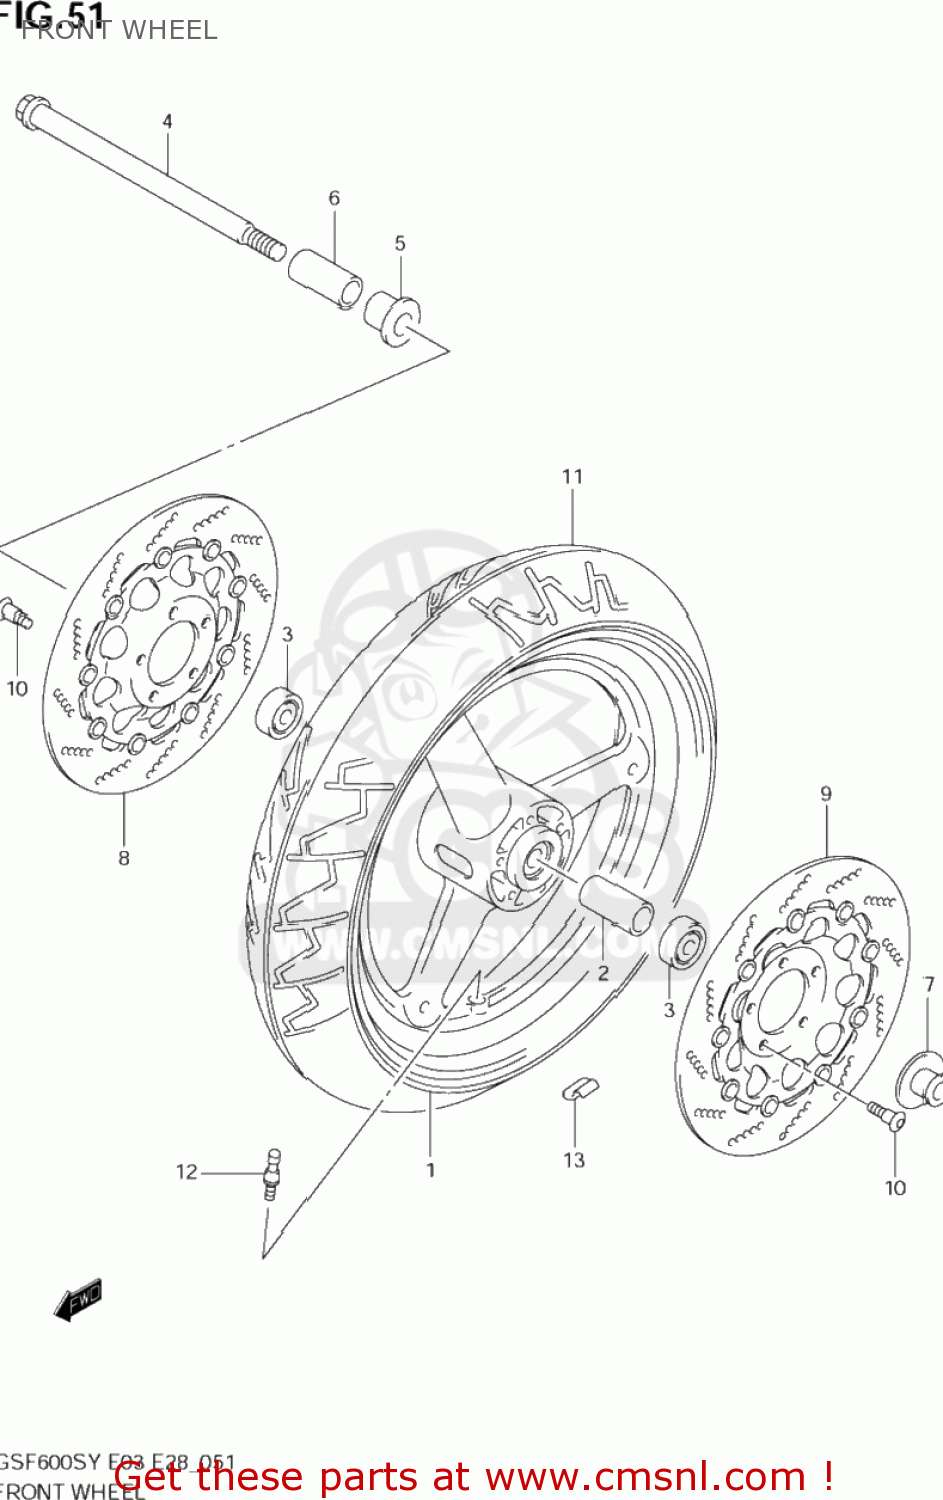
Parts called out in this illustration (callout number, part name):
1	WHEEL,FR.17M/C
2	SPACER(17.5X22.5X73)
3	BEARING
4	AXLE,FR
5	SPACER,FR AXLE,R
6	SPACER,FR AXLE,R
7	SPACER,FR AXLE,L
8	DISC,FR BRAKE,R
9	DISC,FR BRAKE,L
10	BOLT 8X33
11	TIRE,FRONT 120/60 ZR17
12	VALVE ASSY,WHEEL RIM(TR412)
13	BALANCER,WHEEL (10G)
